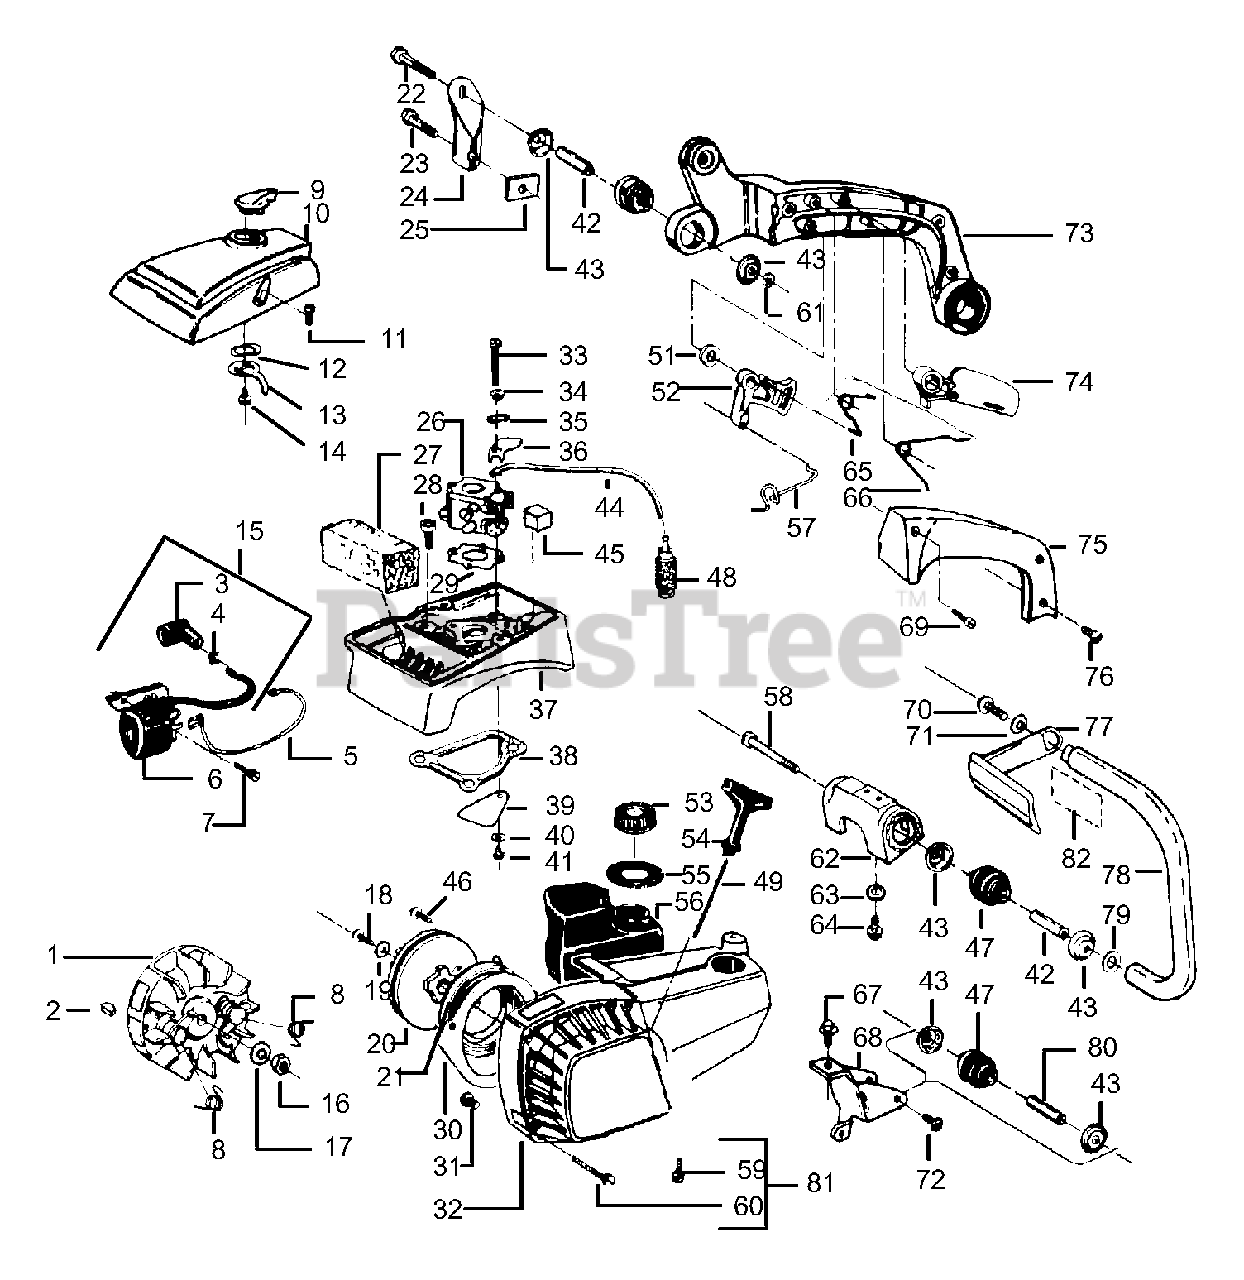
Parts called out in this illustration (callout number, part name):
1	Flywheel Ass'y.
2	Flywheel Key
3	Spark Plug Boot
4	Spark Plug Connector
5	Lead Switch
6	Ignition Module
7	Screw
8	Starter Dog Spring
9	Choke Knob
10	Carb. Cover
12	Wave Washer
13	Choke Lever
15	Spark Plug Lead
18	Screw
20	Starter Pulley
21	Starter Spring
24	Upper Isolator Bracket
25	Isolator Pad
26	Carb.-
27	Air Filter
29	Carb. Gasket
30	Air Intake Baffle
32	Fan Hsg. Kit
35	Wave Washer
36	Choke Shutter
37	Carb. Hsg.
38	Gasket
39	Reed Valve
43	Isolator Cup Line
44	Kit
45	Throttle Wire Boot
46	Rope Ret. Screw
47	Isolator
48	Fuel Pick-Up Ass'y.
49	Rope Kit
52	Throttle Trigger
53	Fuel Cap Ass'y.
54	Starter Handle
56	Fuel Tank Ass'y.
57	Throttle Wire
60	Screw-
62	Lower Isolator Bracket
65	Spring Trigger
66	Throttle Lock out Lever Spring
68	Rear Isolator Bracket
73	Rear Handle- Right
74	Throttle Lock out Lever
75	Rear Handle-Left
77	Handguard
78	Handlebar w/Insert
81	Fan Hsg. Screws Kit
82	Handguard Decal
